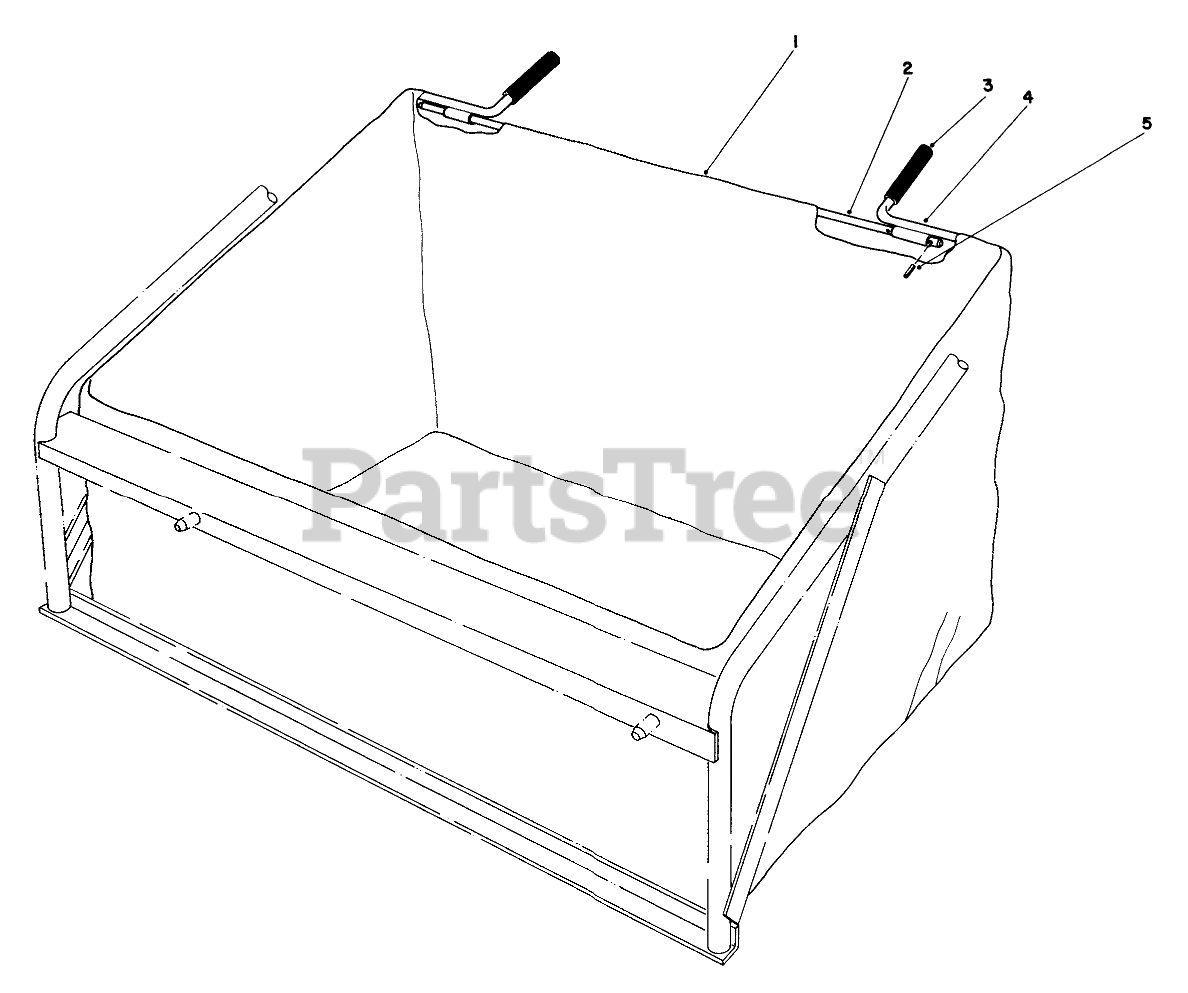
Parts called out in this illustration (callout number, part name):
1	Bag-Leaf Catcher
2	Rod-Bag Frame
3	BAG HANDLE GRIP
4	BAG FRAME WA B
5	PIN-ROLL
